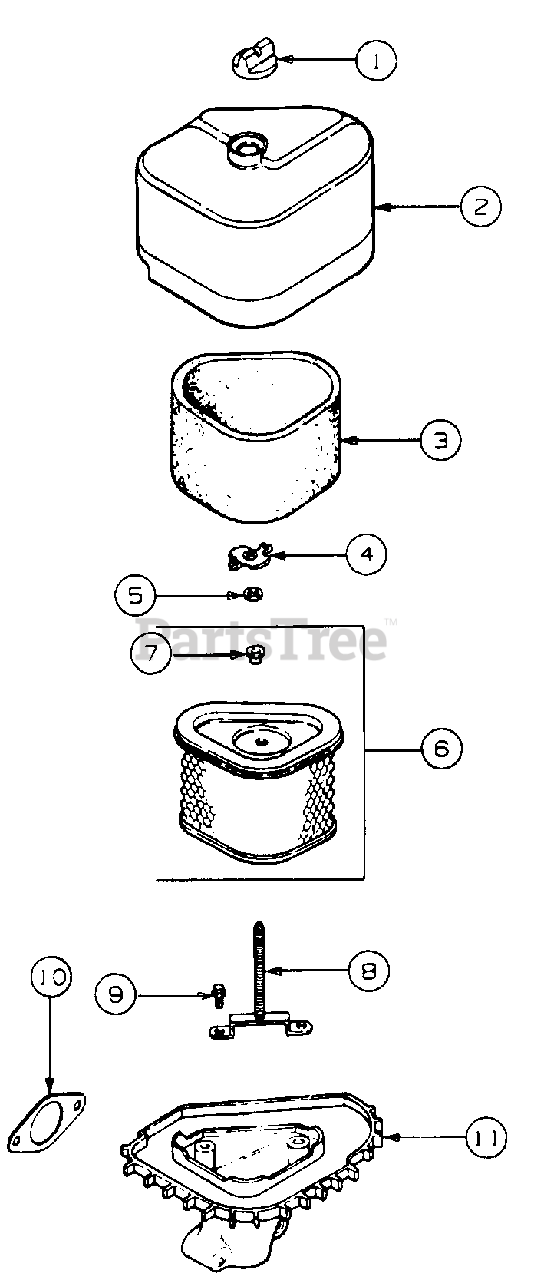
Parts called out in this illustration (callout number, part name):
1	Knob, Air Cleaner Cover
2	Cover, Air Cleaner
3	Precleaner, Element
5	Washer, Plain, 1/4
6	Element, Air Cleaner
8	Stud, Mtg Plate
9	Screw, Mtg Plate Stud
10	Gasket, Air Cleaner
11	Base, Air Cleaner
